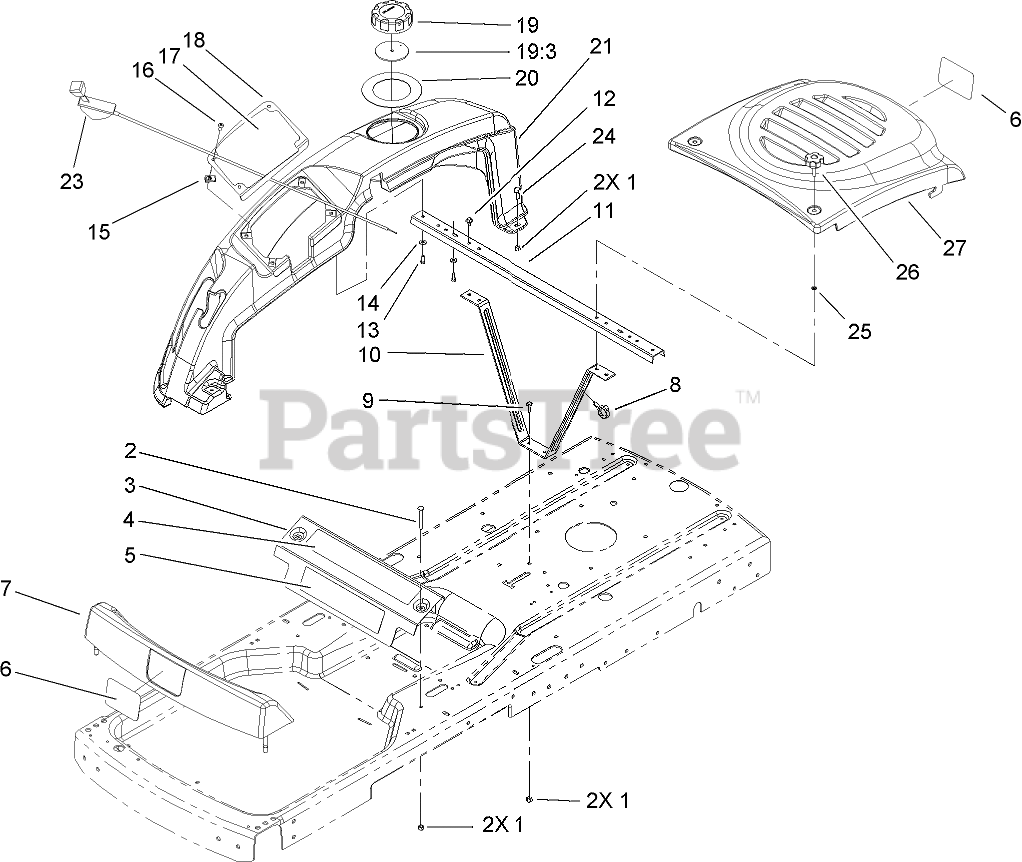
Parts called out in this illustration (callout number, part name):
1	NUT-LOCK, NI
2	SCREW-CARR
3	BRACKET-SUPPORT, FRONT
4	DECAL-DANGER
7	FOOTREST ASM
8	CLAMP-HOSE
9	SCREW-HH
10	BRACE ASM
11	CHANNEL-CROSS
12	SCREW-HHFTF
13	SCREW-PLASTITE
14	WASHER-FLAT
16	SCREW-PRH
17	DECAL-CONTROL
18	PANEL-CONTROL
19	GAS CAP ASM
19:3	GASKET-CAP, GAS
20	SEAL-RUBBER
21	COVER-SIDE, RH
23	CABLE-THROTTLE
24	SCREW-SHOULDER
25	NUT-RETAINER
27	COVER-HOOD
